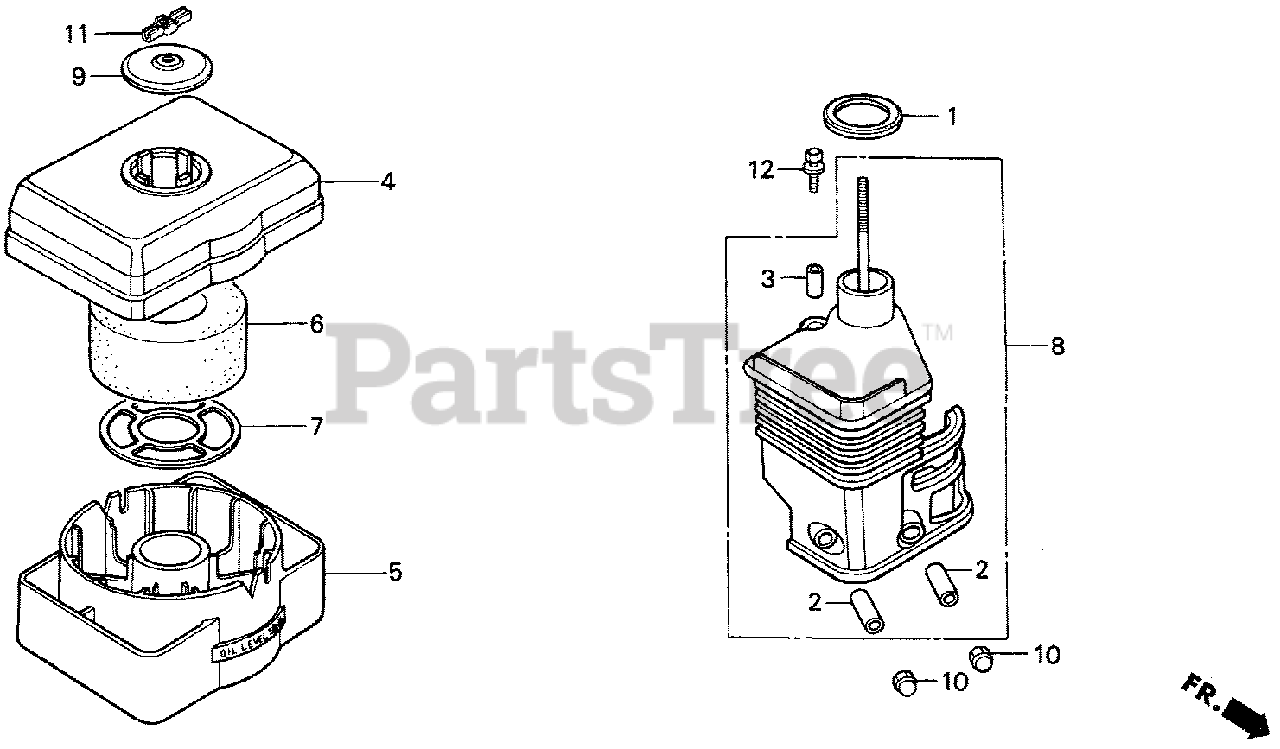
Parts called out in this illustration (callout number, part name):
1	GASKET, ELBOW
2	COLLAR, AIR CLEANER
3	COLLAR B, AIR CLEANER
4	BODY, CLEANER (OIL BATH)
5	PAN, CLEANER OIL (OIL BATH)
6	ELEMENT, AIR CLEANER (OIL BATH)
7	GRID, AIR CLEANER
8	ELBOW, AIR CLEANER
9	CAP, CLEANER
10	NUT, CAP (6MM)
11	WINGNUT, AIR CLEANER COVER
12	BOLT-WASHER (6X20)
